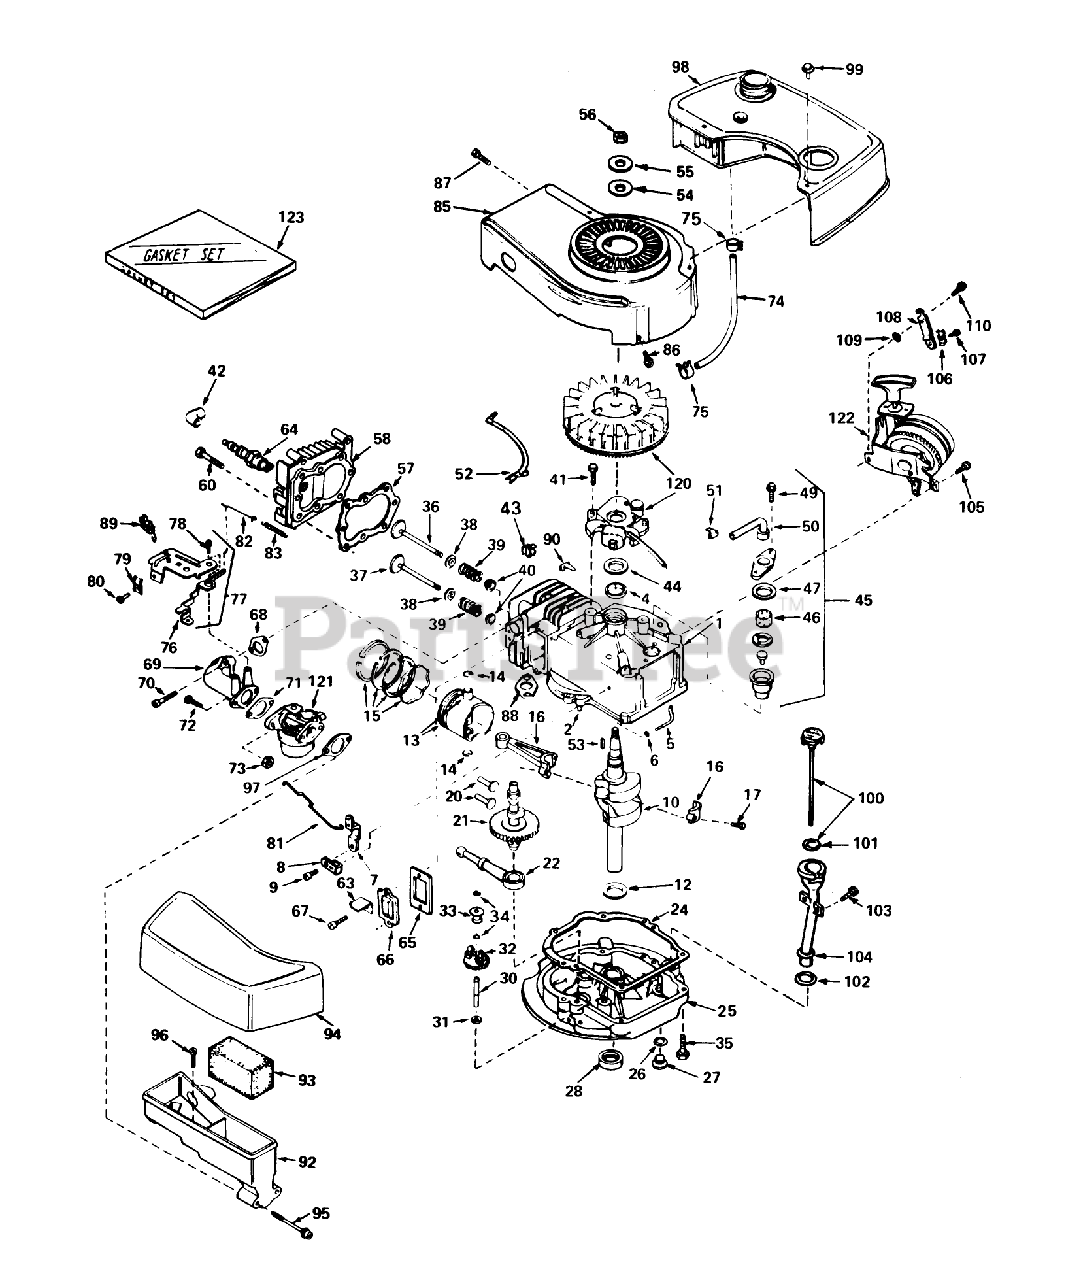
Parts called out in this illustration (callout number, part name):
1	Cylinder Assembly (Incl. Nos. 2, 4 87)
2	Pin-Dowel
4	Seal-Oil
5	Rod, Governor (Incl. No. 36)
6	Washer-Flat
7	Governor Lever
8	Clamp-Lever, Governor
9	Screw
10	Crankshaft
12	Washer-Thrust
13	Piston, Pin Ring Assy. (Incl. Ref. #14 15) (Std.)
13	Piston, Pin Ring Assy. (Incl. Ref. #14 15) (.010 oversize)
13	Piston, Pin Ring Assy. (Incl. Ref. #14 15) (.020 oversize )
14	Ring-Retaining, Piston Pin
15	Ring Set-Piston Std.
15	Ring Set-Piston .010 oversize
15	Ring Set-Piston .020 oversize
16	Rod Assembly, Connecting (Incl. Nos. 17 18)
17	Bolt-Rod, Connecting
20	Lifter-Valve
21	Camshaft(Mech.Comp. Release)
22	Oil Pump ASM
24	Gasket, Mounting
25	Flange Assy., Mounting (Incl. Ref. #26 thru 30)
26	Gasket-Oil Drain
27	Plug Oil Drain
28	Seal-Oil
30	Shaft, Mechanical Governor
31	Washer-Flat
32	Governor Gear ASM
33	Spool-Governor
34	Ring-Retaining
35	Screw (1/4-20 x 1-1/4)
36	Valve, Intake (Incl. Ref. #38, 39 40) (Std.)
36	Valve, Exhaust (1/32" Oversize) (Incl. Nos. 8, 9 10)
37	Valve, Exhaust (Standard) (Incl. Nos. 8, 9 10)
37	Valve, Exhaust (1/32" Oversize) (Incl. Nos. 8, 9 10)
38	Cap-Upper Valve Spring
39	Spring-Valve
40	Cap-Valve, Spring
41	Screw
42	Cover-Spark Plug
43	Clip, Wire
44	Gasket Stator
45	Breather Assy. (Incl. Ref. #46, 47, 49, 50 51 )
46	Element-Breather
47	Gasket-Breather
49	Screw, Hex Hd. w/Conical
50	Tube, Breaker
51	Clip, Breather
52	Wire Ground
53	Key, FIywheel
54	Washer Flat
55	Washer-Spring
56	Hex Nut
57	Oil Fill Tube
58	Head-Cylinder
60	Screw (5/16-18x1-1/2)
63	Retainer Clip
64	Plug, Spark (J17LM or equiv.)
64	Plug, Spark (Champion RCJ-8)
65	Gasket-Breather
66	Cover-Valve
67	Screw
68	Gasket, Intake
69	Pipe, Intake
70	Screw (1/4-20 x 1)
71	Gasket-Carburetor
73	Nut and Lock Washer (1/4-28)
74	Line-Fuel
75	Clamp-Line, Fuel
76	Lever Control
77	Control Assy., Speed (Incl. Nos, 76, 78 89)
78	Screw, Hex Washer Hd Shoulder Self-Tap
79	Conduit
80	Screw (10-32 x 3/8)
81	Link-Throttle
82	Link Governor Spring
83	Spring Governor
85	Housing Blower
86	Screw
87	Screw (10-24 x 9/16)
88	Gasket Exhaust
89	Terminal
90	Clip-Wire
92	Body Air Cleaner
93	Filer, Air
94	Cove, Air Cleaner
95	Screw Fil Hd.
96	Screw, Hex Hd.
97	Gasket-Air Cleaner
98	Tank, Fuel
99	Screw (10-32 x 35/64)
100	Dipstick, Oil (Incl. Ref. #101)(Twist Lock)
101	O-Ring
102	Gasket
103	Screw (10-32 x 1/2)
104	Tube-Oil Fill
105	Screw (1/4-20 x 1/2)
106	Conduit
107	Screw (10-32 x 3/8)
108	Bracker
109	Washer
110	Screw (1/4-20 X 5/8)
120	Magneto
121	Carburetor
122	Starter
123	53024/VAR.16HP O/P
